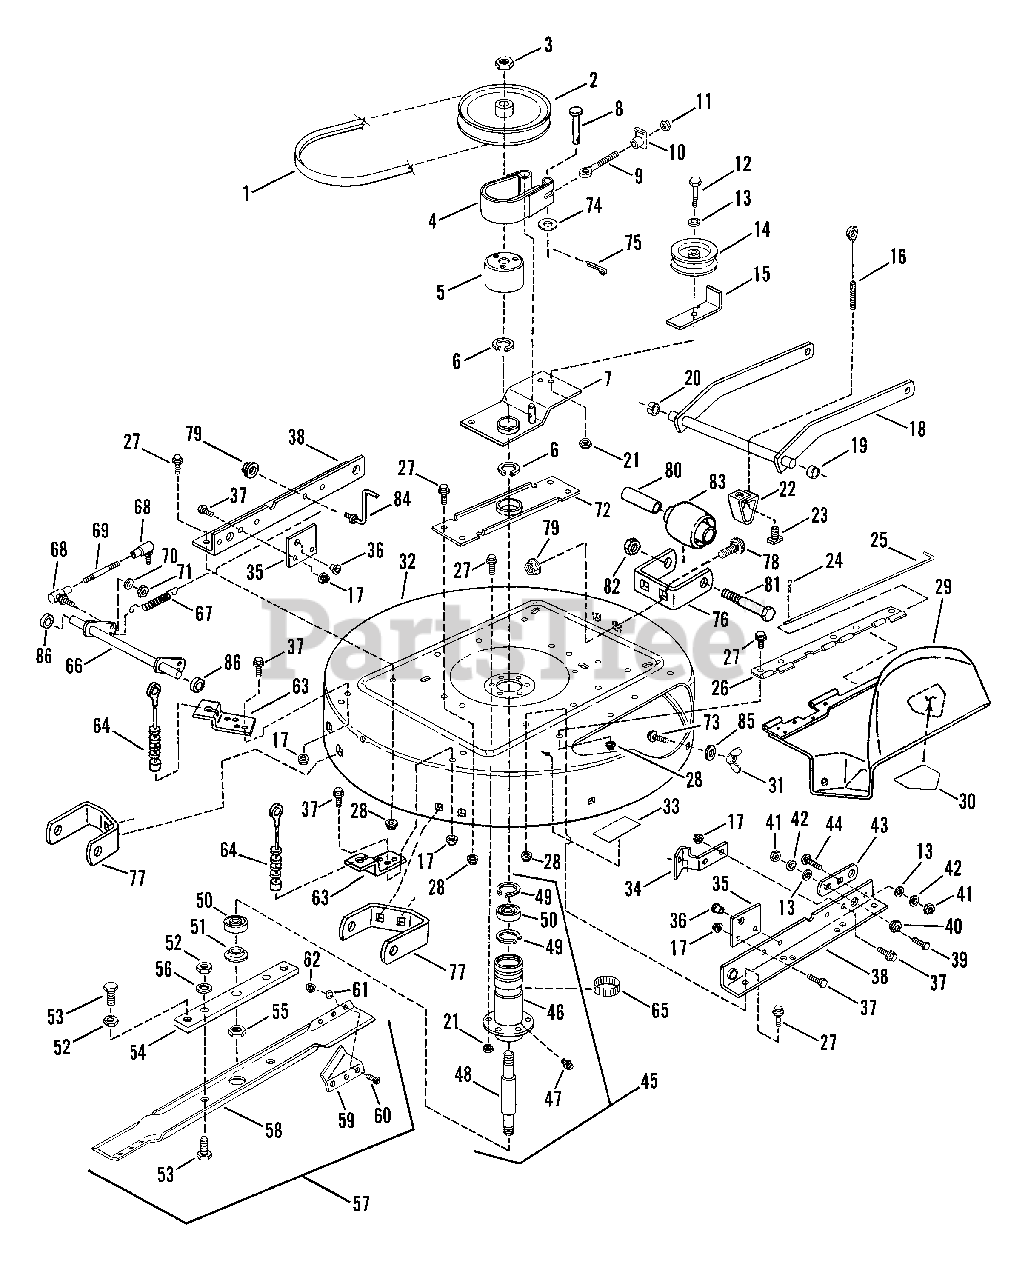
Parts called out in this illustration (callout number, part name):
1	BELT, 33" Drive Kevlar (A-59 61" OD)
2	PULLEY, 8" O.D.
3	NUT, 3/4-16 Hex Jam
4	BAND, Brake Assembly
5	DRUM, Brake
6	RING, 2" External Retaining
7	ARM, Idler
8	PIN, 1/4 x 1-1/4" Clevis
9	BOLT, 1/4-20 Eye
10	NUT, 1/4-20 Tee
11	NUT, 1/4-20 Hex GR 5 YZ
12	SCREW, 3/8-24 x 1-1/2" Hex Head Cap
13	WASHER, 3/8 SAE
14	PULLEY, Idler, 4.12 O.D.
15	GUIDE, Belt
16	CABLE, Front Lift 6.12"
17	LOCKNUT, 5/16-18 Hex Flange
18	LIFT, Front Arm
19	RING, Red
20	RING, Black (Left Side)(5/8" ID x .44" Wide)
21	LOCKNUT, 3/8-24 Hex
22	BRACKET, Front Lift Hanger
23	T-NUT, 5/16-18
24	PIN, Hair 3/32" x 1.5"
25	PIN, Hinge
26	HINGE, Deflector
27	BOLT, 3/8-16 x 3/4" Hex Flange Lock
28	LOCKNUT, 3/8-16 Hex Flange
29	ASSEMBLY, Deflector
30	DECAL, Danger
31	WING-NUT, 5/16-18
32	DECK, Cutting, 33"
33	DECAL, Caution
34	ANCHOR, Brake
35	BRACKET, Cross-Shaft
36	BEARING, Cross-Shaft Bracket
37	BOLT, 5/16-18 x 1/2" Hex Flange Lock
38	RAIL, Side
39	SCREW, 3/8-16 x 1" Hex Head Cap
40	ECCENTRIC, Leveling
41	NUT, 3/8-16 Hex
42	LOCKWASHER, 3/8 Split
43	LINK, Adjustment
44	BOLT, 3/8-16 x 3/4" Carriage
45	ASSEMBLY, Spindle
46	HOUSING, Spindle 5.575" Tall
47	FITTING, Lube (Press into .187" hole, no ball)
48	SPINDLE, 33" Mower Deck 8.26"
49	RING, Retaining EXT 1.75"
50	BEARING, Spindle
51	WASHER, Spindle
52	NUT, 1/2-20 Hex Jam
53	SCREW, 1/2-20 Hex Head Cap
54	HOLDER, Blade
55	NUT, 5/8-18 Hex Lock
56	WASHER, 1/2 Internal Tooth Lock
58	BLADE, 33" Mower Deck
59	AIR-LIFT
60	SCREW, 5/16-24 x 11/16" Machine
61	WASHER, 5/16-24 Internal Tooth Lock
62	NUT, 5/16-24 Hex
63	BRACKET, Rear Lift
64	CABLE, Support 4.25", 8 Spacers
65	RING, Tolerance 2.0"
66	CROSS-SHAFT
67	SPRING
68	BALL-JOINT
69	LINK, Ball Joint
70	WASHER, 1/4 Internal Tooth Lock
71	NUT, 1/4-28 Hex
72	BRACE, Spindle
73	BOLT, 5/16-18 x 3/4" Short Neck Carriage
74	WASHER .28 x .63 x .065 YZ
75	COTTER-PIN, 3/32 x 3/4"
76	BRACKET, Gage Wheel
77	BRACKET, Gage Wheel
78	BOLT, 5/16-18 x 1/2" Short Neck Carriage
79	NUT, 5/16-18 Hex Flange Lock
80	SPACER .625 OD x .423 ID x 3" L
81	SCREW, 3/8-24 x 3-3/4" H.H.C.
82	LOCKNUT, 3/8-24 Hex
83	WHEEL, Gage
84	GUIDE, Belt
85	WASHER, 5/16 Flat
86	SPACER
